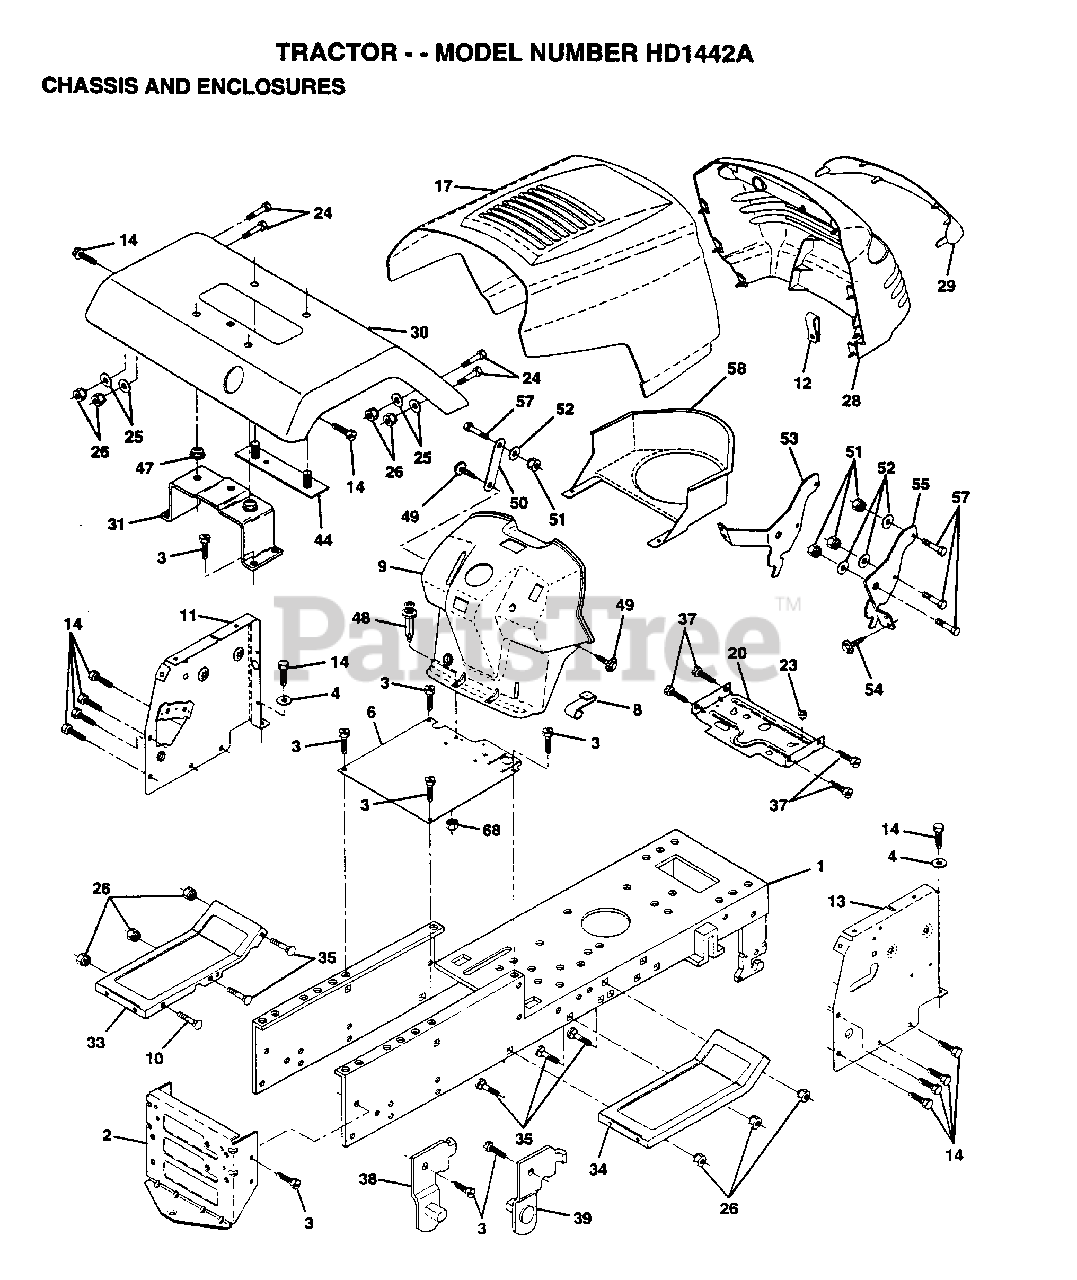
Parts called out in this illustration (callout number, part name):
1	CHASSIS.WLD.11GA
3	SCREW
4	WASHER
8	"CLIP,INSULATOR"
12	CLIP.TINNERMAN
13	PANEL.DASH.RH
14	SCREW LT
20	PLATE.MTG.BTRY.TK
24	BOLT
25	WASHER
26	NUT
29	LENS GRILLE
30	FENDER PNT
31	BRKT.ASM.FENDER
33	FOOTREST.LH.LT/GT
34	FOOTREST.RH.LT/GT
35	BOLT
37	SCREW TI
38	BRACKET ASM LH
39	BRACKET ASM RH
44	STRAP ASM FENDER
47	NUT-PUSH YT
48	RIVET.PUSH.PLATE
49	SCREW HEX CRT
50	BRACE SUPT DASH
51	NUT
52	WASHER
53	BRACKET.GRILLE.LH
55	BRACKET.GRILLE.RH
58	DUCT AIR 12-15H
68	NUT
